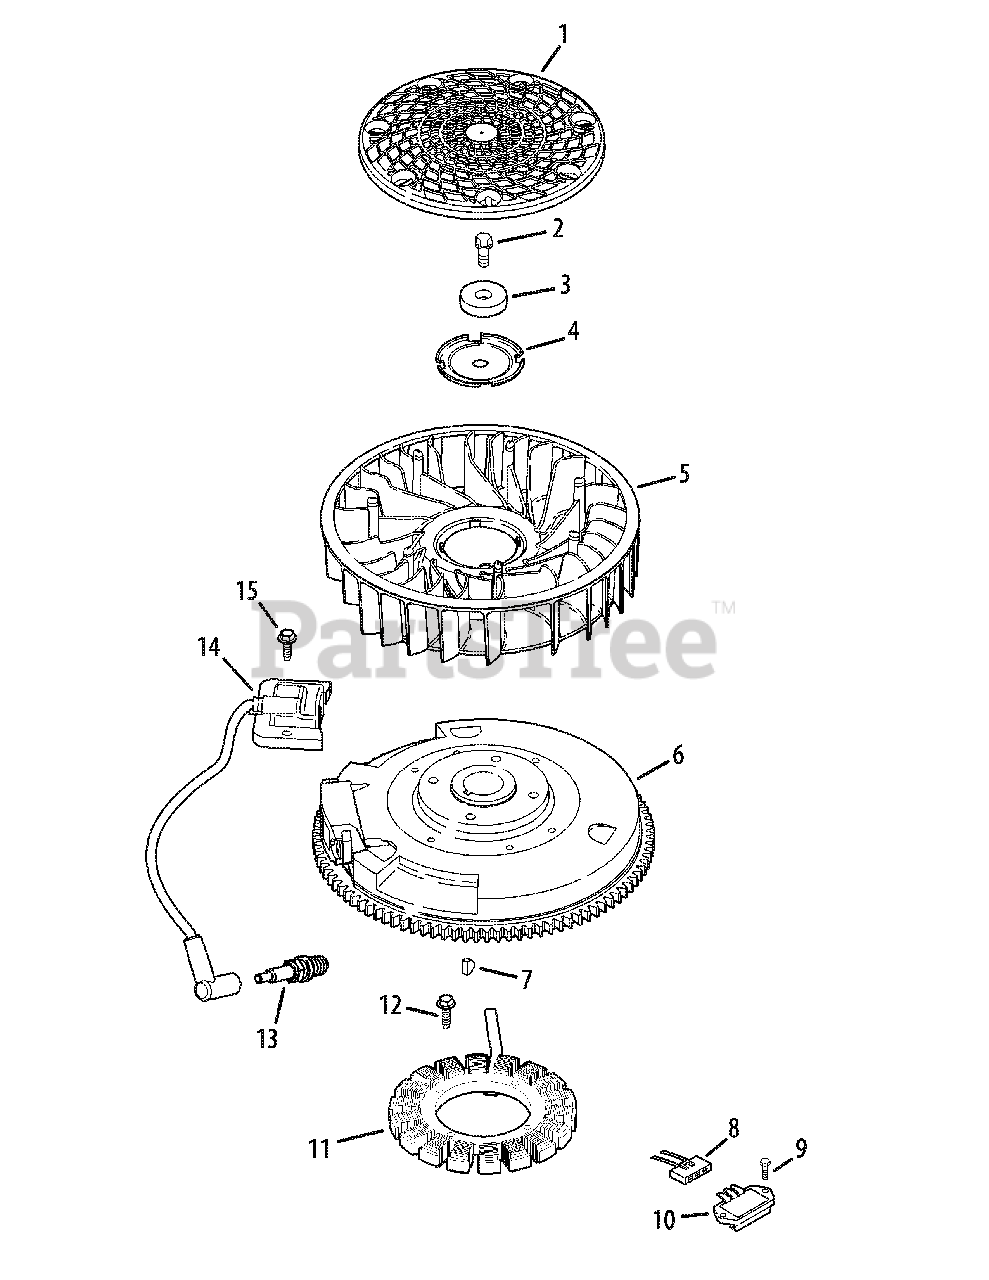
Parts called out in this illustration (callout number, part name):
1	Screen, grass
2	Screw, hex. flange M10x1.5x45
3	Washer, plain 3/8"
4	Plate, fan mounting
5	Fan
6	Flywheel
8	Connector (3 contact)
9	Screw, heavy hex. flange M5x0.8x16
10	Rectifer-regulator
11	Kit, 15 amp stator
12	Screw, hex. head M5x0.8x25
13	Spark plug
14	Module, ignition
15	Screw, hex. flange M5x0.8x20
